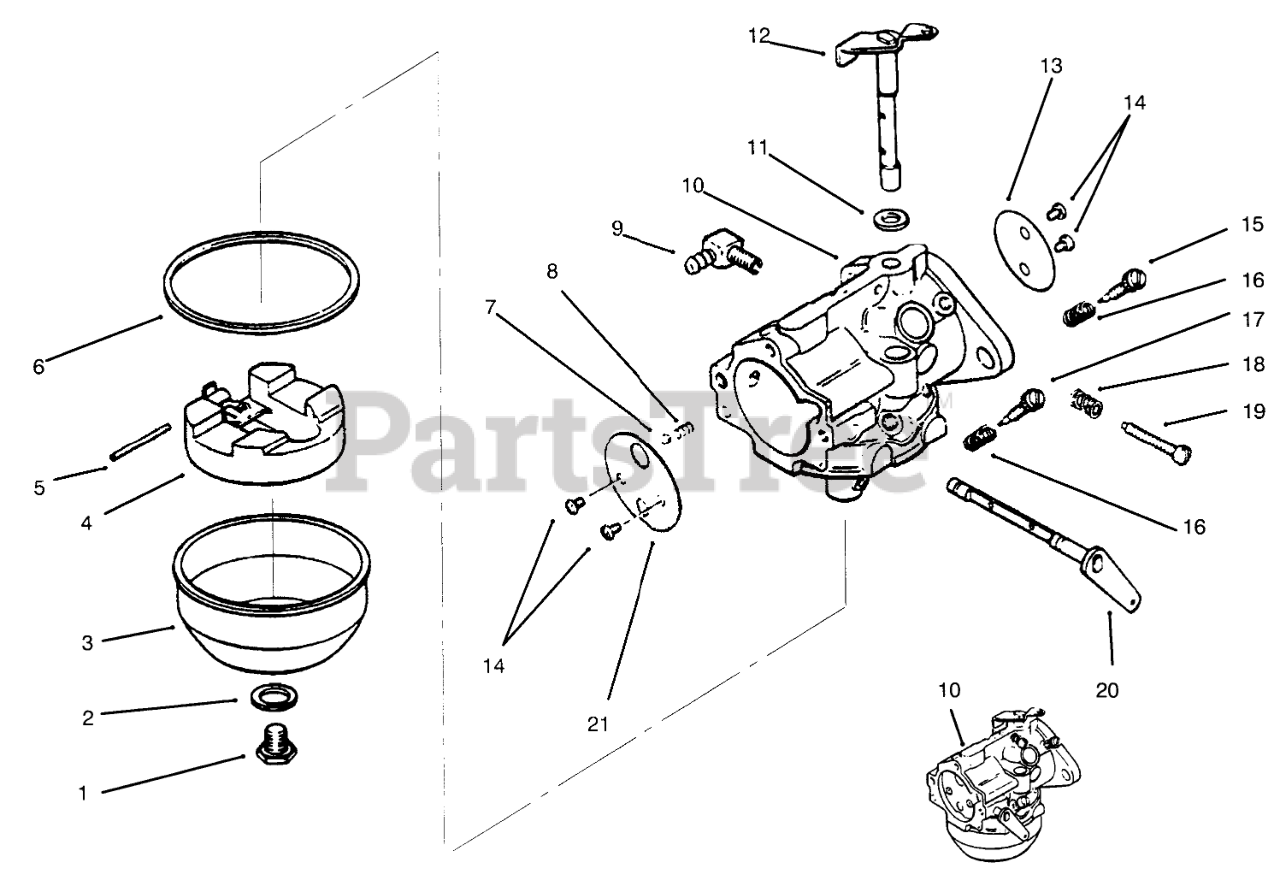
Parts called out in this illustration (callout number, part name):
1	Screw
2	Gasket
3	Bowl-Fuel
4	Kit-Float
6	Gasket
7	Ball
8	Spring
10	Carburetor ASM Incl 5-8
10	Carburetor Complete
12	Shaft Lever/Seal Incl 11
12	Shaft Lever & Seal
13	Plate-Throttle
14	Screw
15	Needle-Idle Fuel Adj
16	Spring
17	Main-Needle
18	Spring-Adj
19	Screw-Idle Speed Adj
20	Shaft-Choke
21	Plate-Choke
